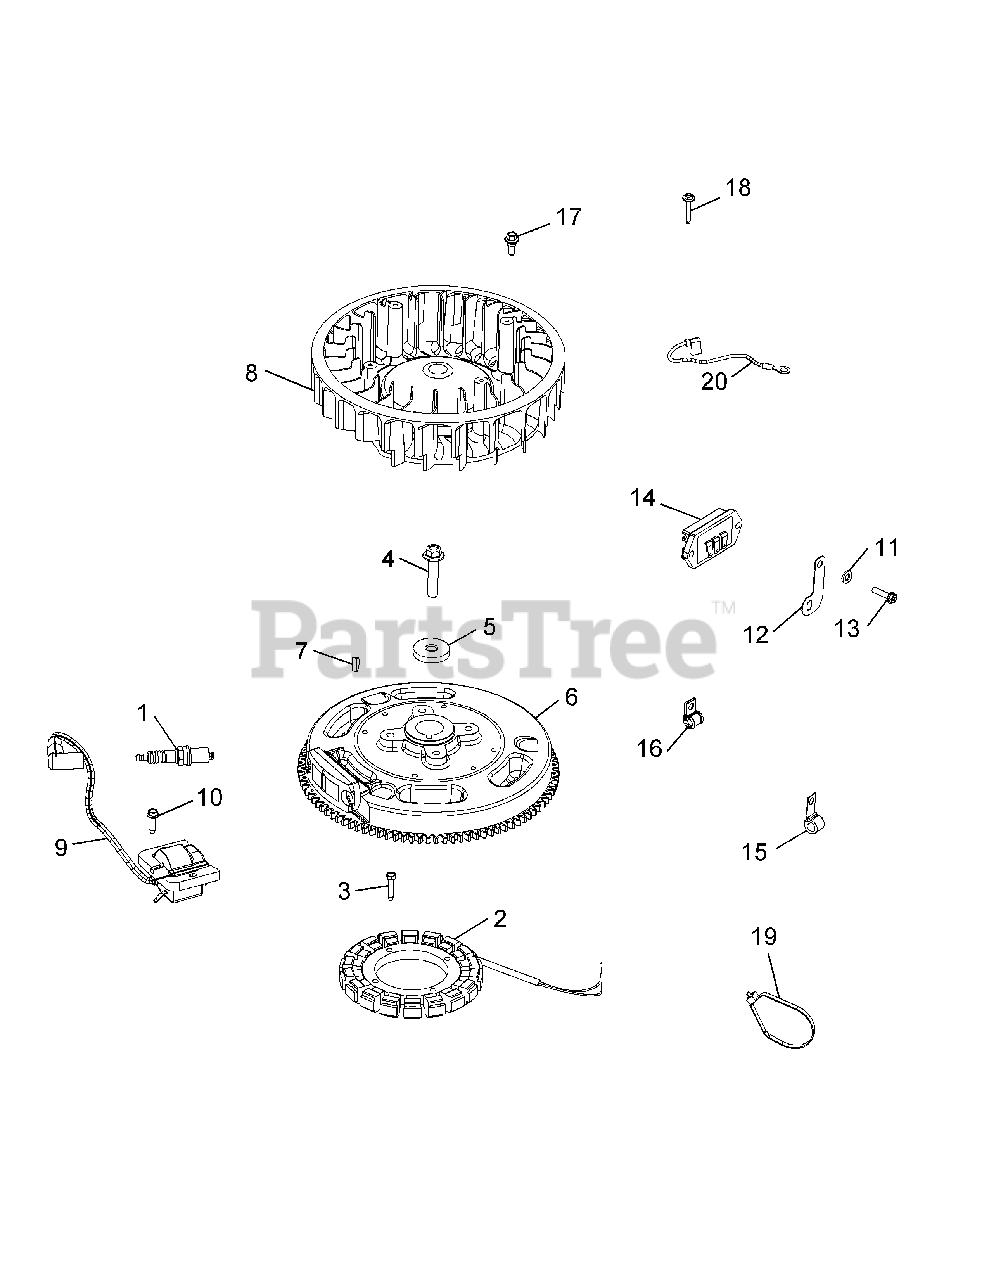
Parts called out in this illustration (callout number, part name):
2	15 Amp Stator Kit
3	Thread Forming Screw
4	Flange Screw, M10 x 1.5 x 45
5	Flat Washer, 13/32"
7	Key, 3/16 x 5/8
9	Ignition Module Kit
10	Thread Forming Screw
11	Flat Washer, 1/4
12	Ground Strap Bracket
13	Hi-Lo Hex Flange Screw
14	Rectifier Regulator
15	Cable Clip
17	Shoulder Bolt
18	Flange Screw, M4 x .7 x 25
